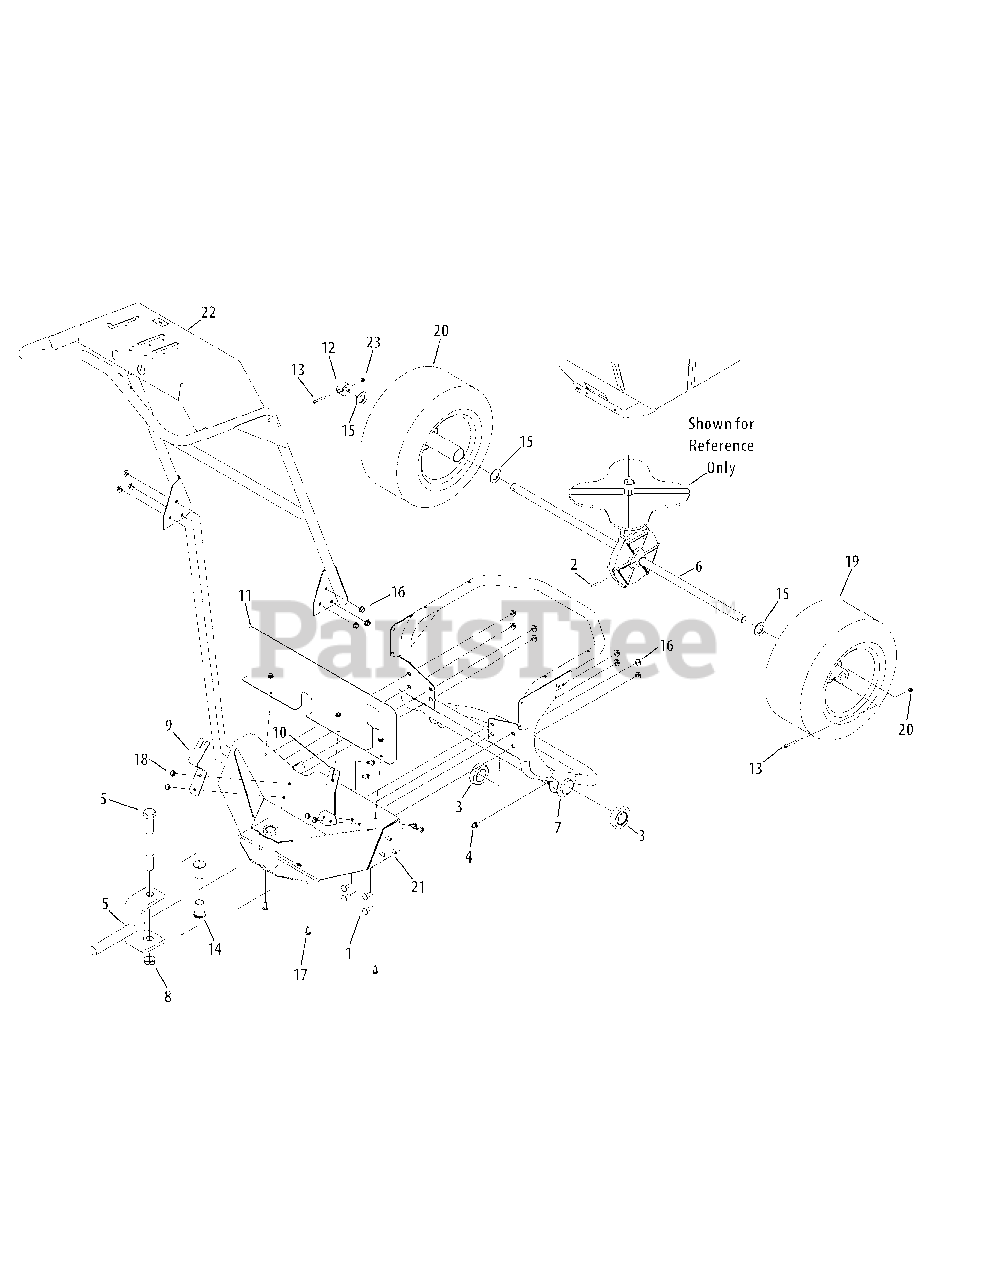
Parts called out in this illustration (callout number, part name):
1	Carriage Bolt, 5/16-18 x 3/4
2	Roller Pin, 5/32 x 1-1/4
3	Axle Bearing, 3/4 x 1-3/8
4	Grease Fitting, 1/4-28
5	Hex Screw, 3/4-16 x 6.50
6	Front Axle
7	Front Frame
7	Grease Fitting, 1/4-28 x 3/16
7	Axle Bearing
8	Jam Nut, 3/4-16
9	Shut-Off Cable Bracket
10	Deflector Cable Bracket
12	Shaft Collar, 3/3 x 1-1/4
13	Socket Screw, 10-24 x 1.25
14	Flange Bushing
15	Flat Washer, .890 x 1.50 x .093
16	Flange Nut, 5/16-18
17	Carriage Bolt, 1/4-20 x 3/4
18	Flange Nut, 1/4-20
19	Wheel, 13 x 6.50-6
20	Wheel, 13 x 6.50 x 6
21	Pivot Bracket
22	Handle Assembly
23	Hex Lock Nut, #10-24
